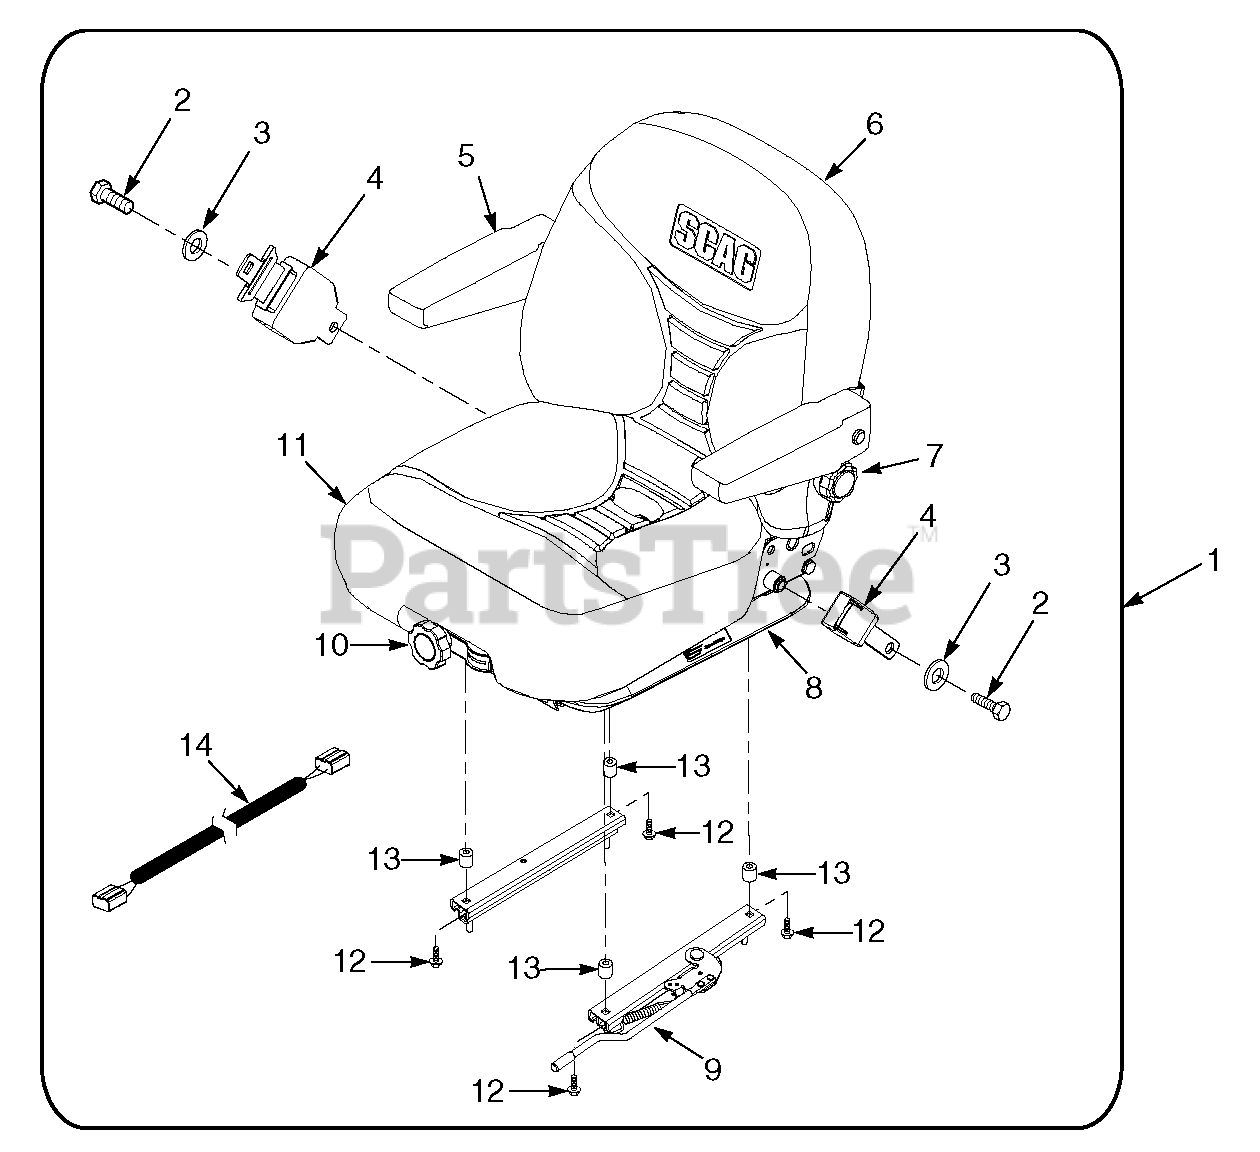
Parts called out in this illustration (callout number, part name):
1	Suspension Seat Assembly w/seat belt
2	Bolt, Hex Head 7/16-20 x 1"
3	Flatwasher, 7/16-.500 x 1.25 x .083
4	Retractable Seat Belt
5	Armrest Only
5	Armrest Assembly Kit, LH
5	Armrest Assembly Kit, RH
6	Back Cushion Kit
7	Lumbar Kit
7	Knob Kit
8	Shock Absorber Kit
9	Seat Adjustment, Track Set
10	Weight Adjustment Kit
10	Knob Kit
11	Seat Cushion Kit
11	Seat Drain Kit (Included with Seat Cushion)
12	Bolt, Hex Head 5/16-18 x 1-3/4"
13	Spacer
14	Wire Harness Adapter
